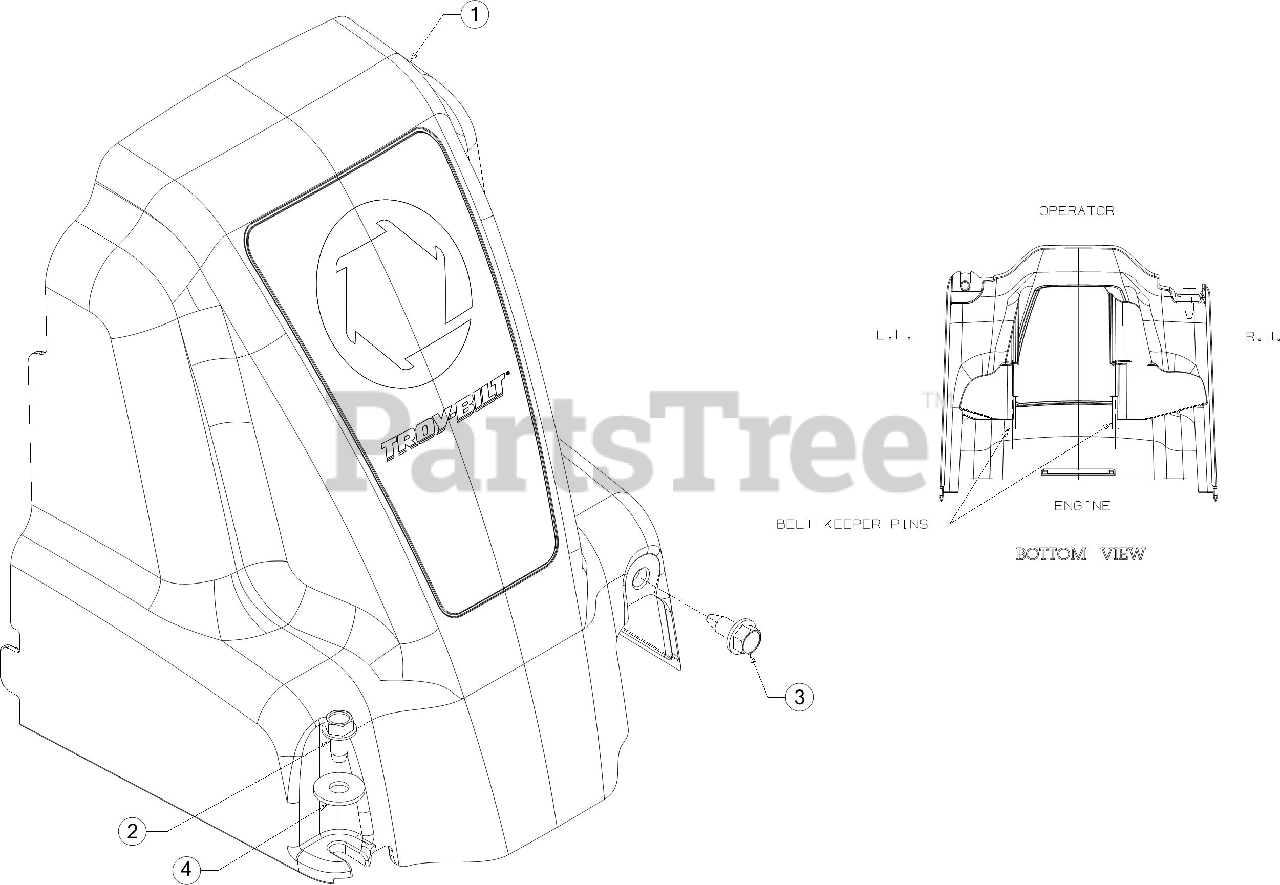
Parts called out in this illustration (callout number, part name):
1	BELT COVER ASSEMBLY
2	SCREW 1/4-20 X.500
3	SCREW 1/4-14 X .625
4	FLAT WASHER .28 ID X .74 OD X .063
